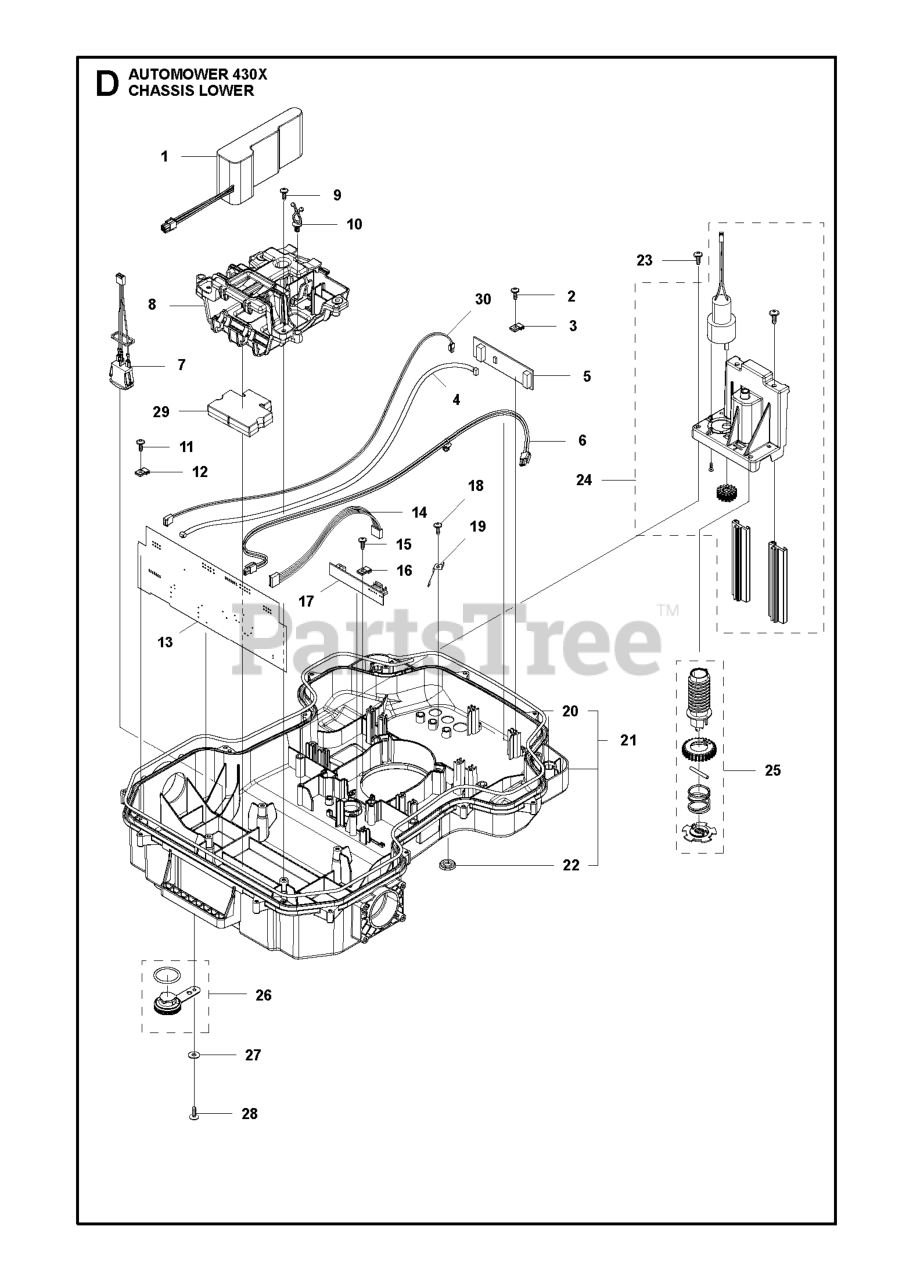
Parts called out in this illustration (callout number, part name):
1	BATTERY 588146401 PACKED
2	SCREW 14MM
3	CLAMP PCB
4	LOOM LOOP SENSOR
5	PRINTED CIRCUIT ASSY LOOP SENS
6	LOOM CHARGING LINK HIGH CHARGI
7	LOOM ON/ OFF
8	HOLDER BATTERY
9	SCREW ITXPANT
10	HOLDER TWIST LOCK
11	SCREW 14MM
12	CLAMP PCB
13	PRINTED CIRCUIT ASSY PCBA MAIN
14	LOOM HEIGHT ADJUSTMENT
15	SCREW 14MM
16	CLAMP PCB
17	PRINTED CIRCUIT ASSY PCBA CUTT
18	SCREW 14MM
19	SPRING GUIDE HEIGHT ADJUSTMENT
20	SEALING STRIP
21	CHASSIS KIT LOWER
22	GROMMET M16
23	SCREW 14MM
24	MOTOR ASSY HEIGHT MOTOR
25	SCREW KIT
26	PLUG KIT
27	WASHER
28	SCREW ITXPANT
29	WEIGHT CENTER
30	WIRING ASSY LED LIGHT EXTENSIO
